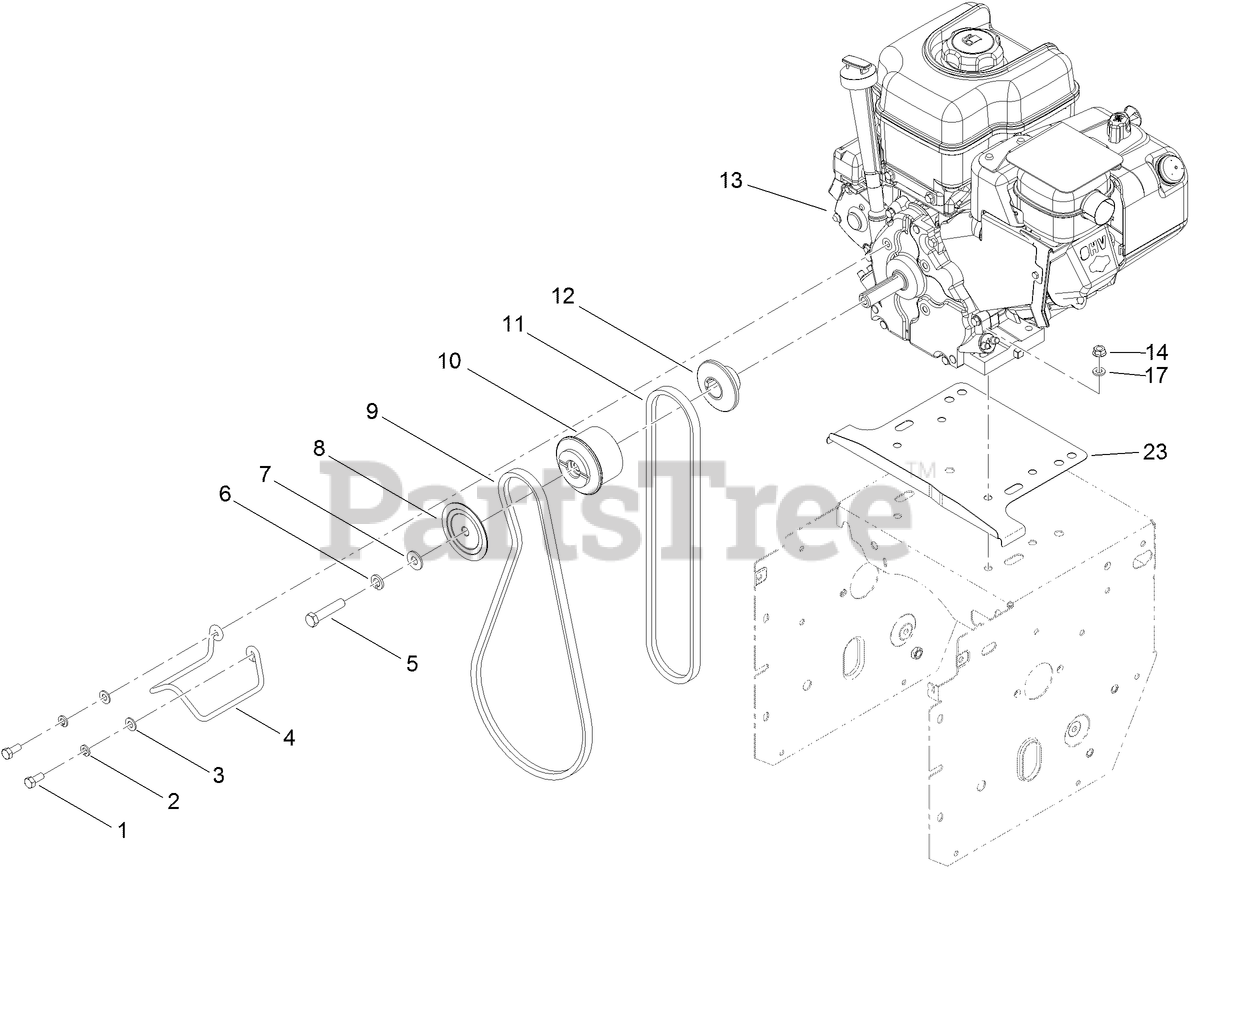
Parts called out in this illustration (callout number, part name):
1	SCREW-HH
2	WASHER-LOCK
3	WASHER-PLAIN
5	SCREW-HH
6	WASHER-LOCK
7	WASHER-FLAT
8	SHEAVE-HALF, IMPELLER
9	BELT-V
10	PULLEY-ENGINE, CENTER
11	V BELT-TRACTION
12	SHEAVE-HALF, TRACTION
14	NUT-HF
17	WASHER-FLAT
23	SHIELD-DRIVE
